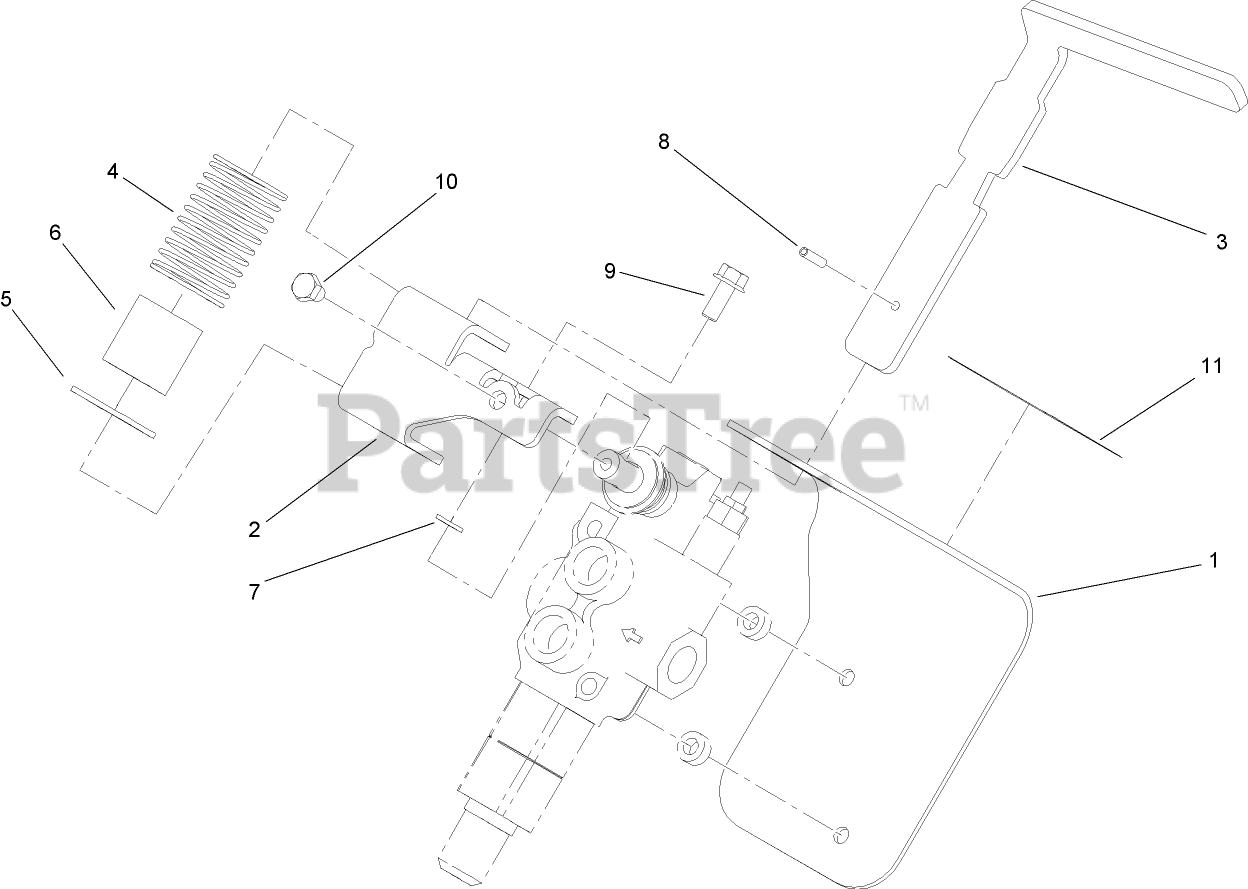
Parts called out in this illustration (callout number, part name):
1	BRACKET-AUXILIARY
2	MOUNT-LEVER, AUXILIARY
3	HANDLE-LEVER, AUXILIARY
4	SPRING
5	RETAINER-SPRING, AUXILIARY
6	TUBE-SPRING
7	WASHER-LOCK
8	PIN-SPRING
9	SCREW-HHF
10	SCREW-HH
11	DECAL-AUXILIARY, CE
